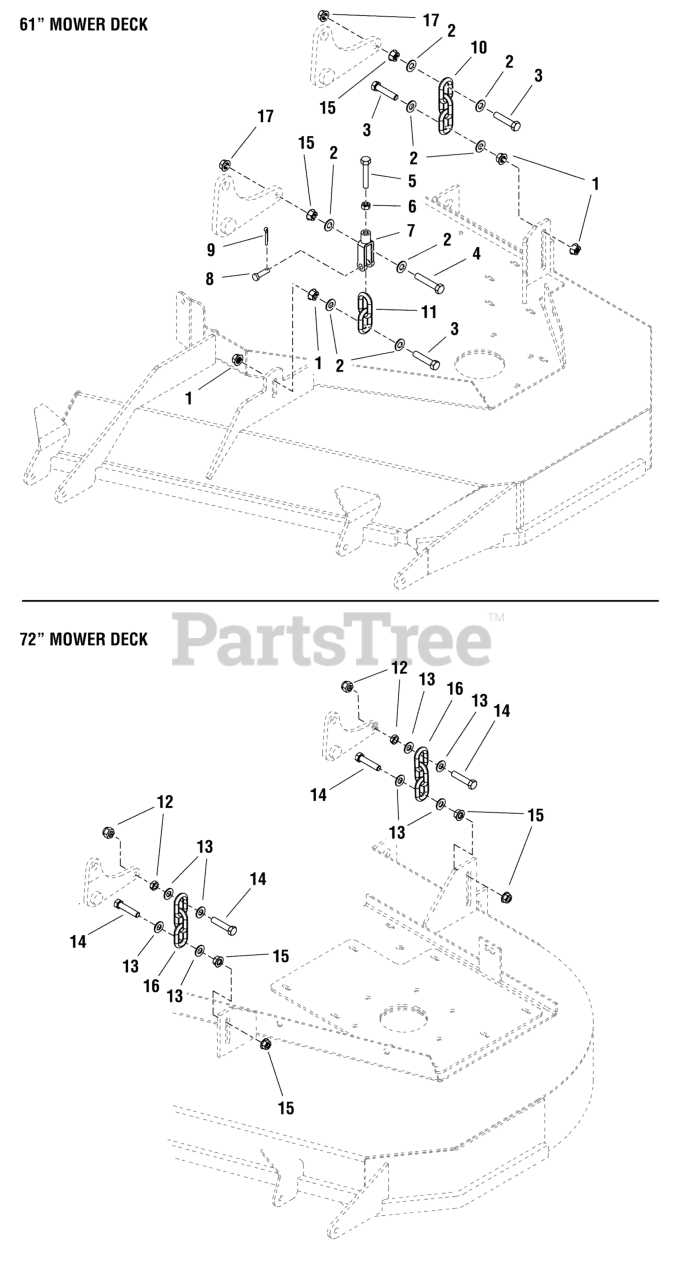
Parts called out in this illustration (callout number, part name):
1	NUT, 3/8-16 HEX SERRATED FLANGE
2	WASHER, 3/8 SAE
3	BOLT, 3/8-16 X 1-3/4" GD5 CZ
4	BOLT, 3/8-16 X 2, GD5, CZ
5	BOLT, 5/16-18 X 2 GD5 TFL
6	NUT, 5/16-18 HEX
7	CLEVIS, 5/16-18, 3/8 PIN HOLE
8	PIN, CLEVIS, 3/8 X 1-1/8
9	PIN, 3/32 X .750, COT, ZINC/CLEAR
10	CHAIN, 5/16 GD30, 3 LINKS
11	CHAIN, 5/16 GD30, 2 LINKS
12	NUT, 3/8-16 HEX SERRATED FLANGE
13	WASHER, 3/8 SAE
14	BOLT, 3/8-16 X 1-3/4" GD5 CZ
15	NUT, 3/8-16 HEX JAM
16	CHAIN, 5/16 GD30, 3 LINKS
17	NUT, 3/8-16 HEX NYLOCK FLANGE
